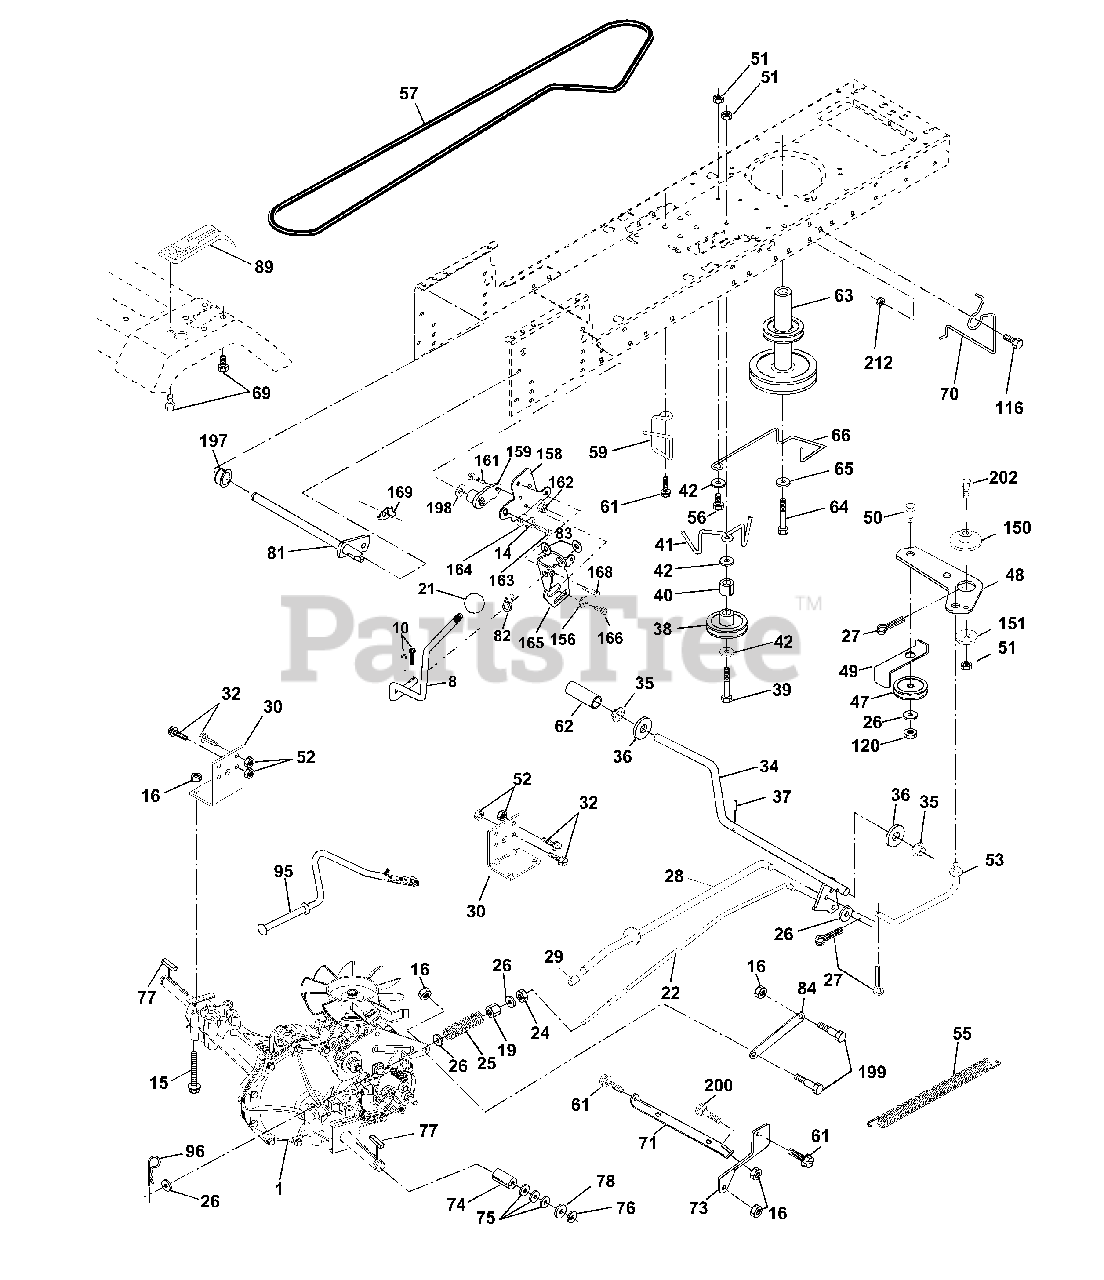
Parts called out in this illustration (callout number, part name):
8	Rod Shift Hydro LT
10	Pin Cotter 1/8 x 1 CAD
14	Washer Lock Hvy Helical
15	Bolt, Hex FLGHD 5/16-18 Gr. 5
16	Nut Lock Hex W/Ins 5/16-18 Unc P
19	Nut Lock Hex W/Wsh 3/8-16 Unc
21	Knob, Round 1/2-13
22	Rod, Brake Hydro
24	Nut
25	Spring, Brake Rod
26	Washer
27	Pin Cotter 1/8 x 3/4 CAD.
28	Rod, Parking Brake
29	Cap, Parking Brake
30	Bracket, Transaxle
32	Bolt Hex Hd 5/16-18 Unc x 3/4
34	Shaft, Foot Pedal
35	Bearing, Nylon
36	Washer
37	Pin, Roll
38	Pulley, Idler, Flat
39	Bolt
40	Spacer, Split
41	Keeper, Belt Idler
42	Washer 13/32 x 13/16 x 12 Gauge
47	Pulley, Idler, V-Groove
48	Bellcrank Clutch Grnd Drv STL
49	Retainer, Belt
50	Bolt
51	Nut Crownlock 3/8-16 UNC
52	Nut Crownlock 5/16-18 UNC
53	Link, Clutch
55	Spring, Return, Clutch
56	Bolt Fin Hex 3/8-16 UNC x 1-1/4
57	V-Belt, Ground Drive
59	Keeper, Center Span
61	Screw Thdrol. 3/8-16 x .75
62	Cover, Pedal
63	Pulley, Engine
64	Bolt, Hex
65	Washer
66	Keeper Belt Engine
69	Screw
70	Guide Belt
71	Strap Torque Lh Hydro
73	Strap Torque Rh Hydro
74	Spacer, Axle
75	Washer 25/32 x 1-1/4 x 16 Gauge
76	E-Ring
77	Key, Square
78	Washer 25/32 x 1-5/8 x 16 Gauge
81	Shaft Asm. Cross Hydro
82	Spring Torsion T/A
83	Washer 17/32 x 3/4 x 16 Ga.
84	Link Transaxle
89	Console, Hydro
95	Control Asm Bypass Hydro
96	Retainer Spring 1" Zinc/Cad
116	Bolt RDHD Sqnk 3/8-16
120	Nut Lock Flg. 3/8-16 Unc
150	Bushing Bellcrank Grd Drive
151	Washer 13/32 x 2 x 10 Ga.
156	Washer Srrted 5/16 ID x 1.125
158	Bracket Shift Mount
159	Cupholder
161	Bolt Rdhd Sqnk 1/4-20 x 3/4 Gr 5
162	Nut Crownlock 1/4-20 Unc
163	Bolt Hex Fin 1/4-20 Unc x 1 Gr 5
164	Washer 5/8 x .281 x 10 Ga
165	Bracket Pivot Lever
166	Screw 5/16-18 x 5/8
168	Bolt Shoulder 5/16-18 x .561
169	Plate Fastening Lt
197	Nyliner Snap-In 5/8" ID
198	Washer Nyl 7/8 ID x .105
199	Bolt Shoulder 5/16-18 Unc
200	Bolt Rdhd Sqnk 5/16-18 Unc x 1
202	Bolt Carr Sh 3/8-16 x 1-1/2 Gr 5
212	Nut Hex Flange Lock
